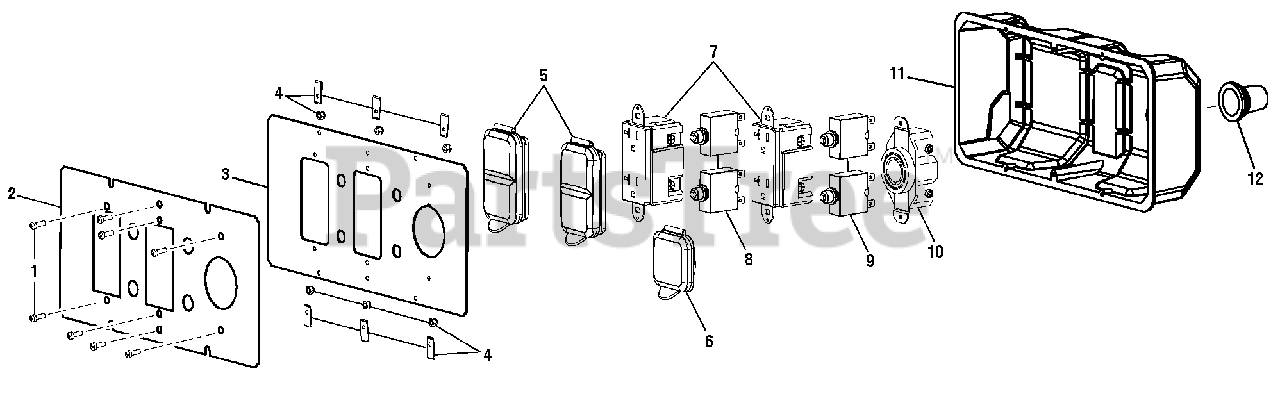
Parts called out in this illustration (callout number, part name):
1	Screw (6-20 x 3/8 in.)
2	Label (Power Outlet)
3	Front Panel
4	U-Clip Nut
5	Outlet Cover (120 Volt)
6	Outlet Cover (240 Volt)
7	Duplex Receptacle (120 Volt)
8	Circuit Breaker, 20 Amp
9	Circuit Breaker, 25 Amp
10	Twist Lock Receptacle (240 Volt)
11	Control Box (Back Panel)
12	Rubber Boot
